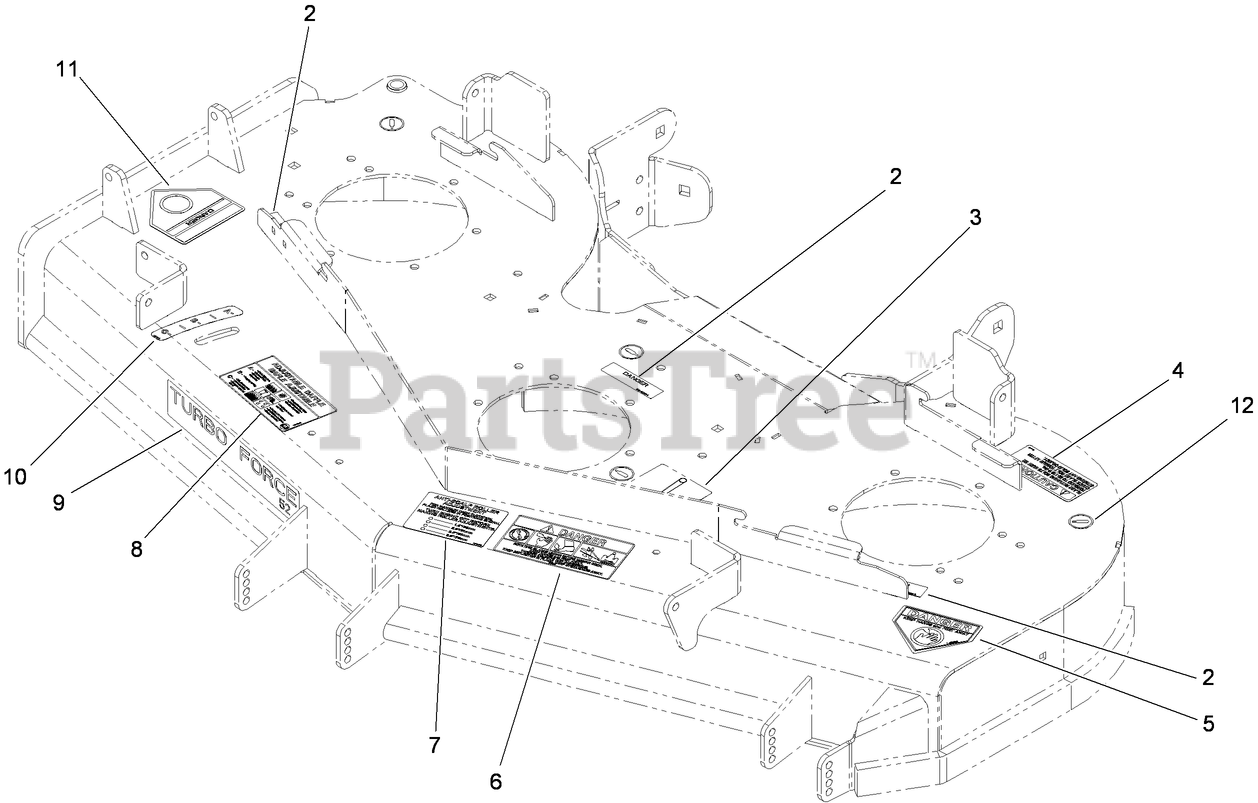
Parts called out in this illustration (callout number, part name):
2	DECAL-COVER, MISSING
3	DECAL-ROUTING, DECK BELT
4	DECAL-TORQUE
5	DECAL-DANGER
6	DECAL-DANGER, THROWN OBJECT
7	DECAL-SCALP, ANTI
8	DECAL-ADJUSTMENT, BAFFLE
10	DECAL-SETTING, BAFFLE
11	DECAL-DANGER
12	DECAL-GREASE
